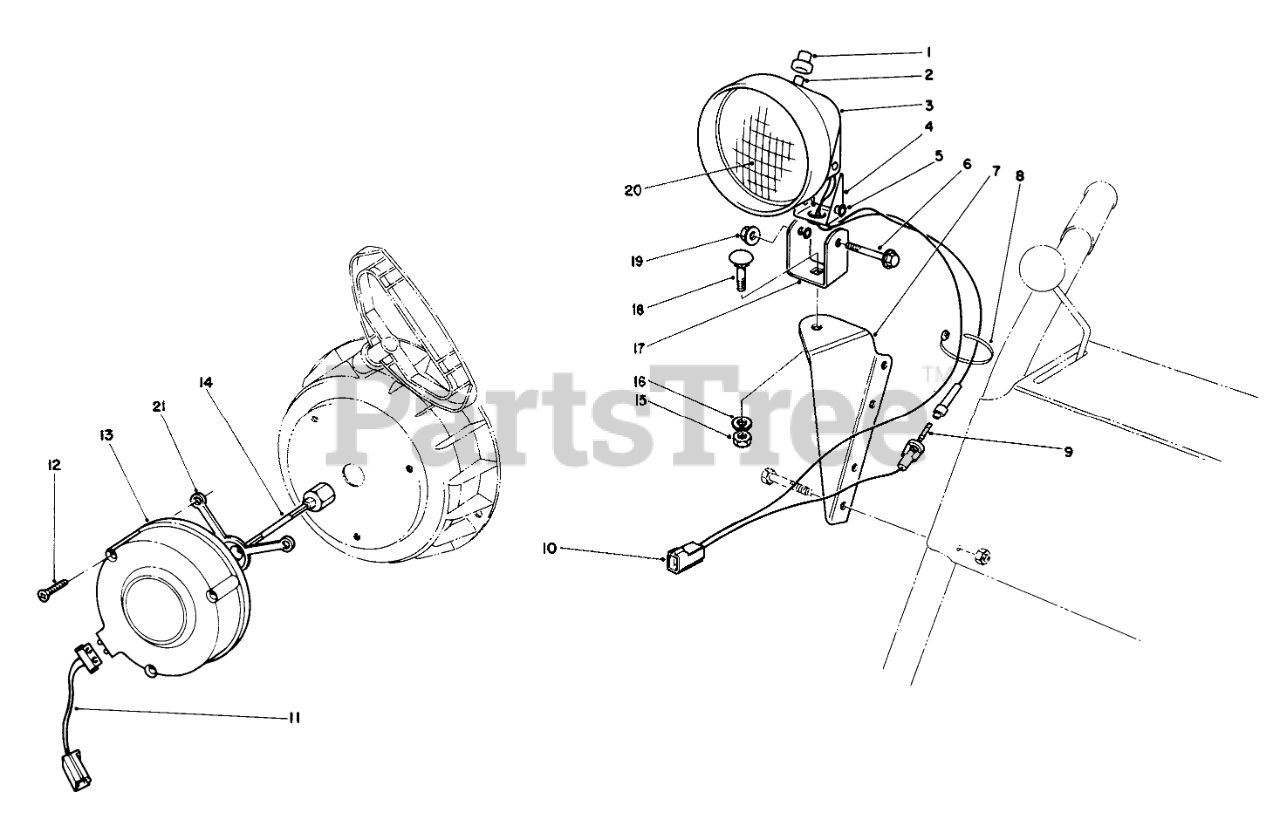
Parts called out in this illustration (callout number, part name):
1	BOOT-SWITCH
2	SWITCH ASM
3	Bucket-Headlamp
4	TO BE DISCONTINED-NOT NEEDED ON PRODUCT
5	WASHER-LOCK
6	SCREW-HH
7	LAMP MOUNT B
8	TIE-CABLE
9	Fuse-7-1/2 Amp.
10	WIRE ASM
11	Connector-Wire
12	SELF TAPPING SCREW
13	Alternator
14	Shaft-Alternator, 3 Inch
15	NUT-HEX
16	WASHER-LOCK
17	BRACKET
18	BOLT-CARR
19	NUT-HF
20	BEAM-SEALED
21	SPACER
